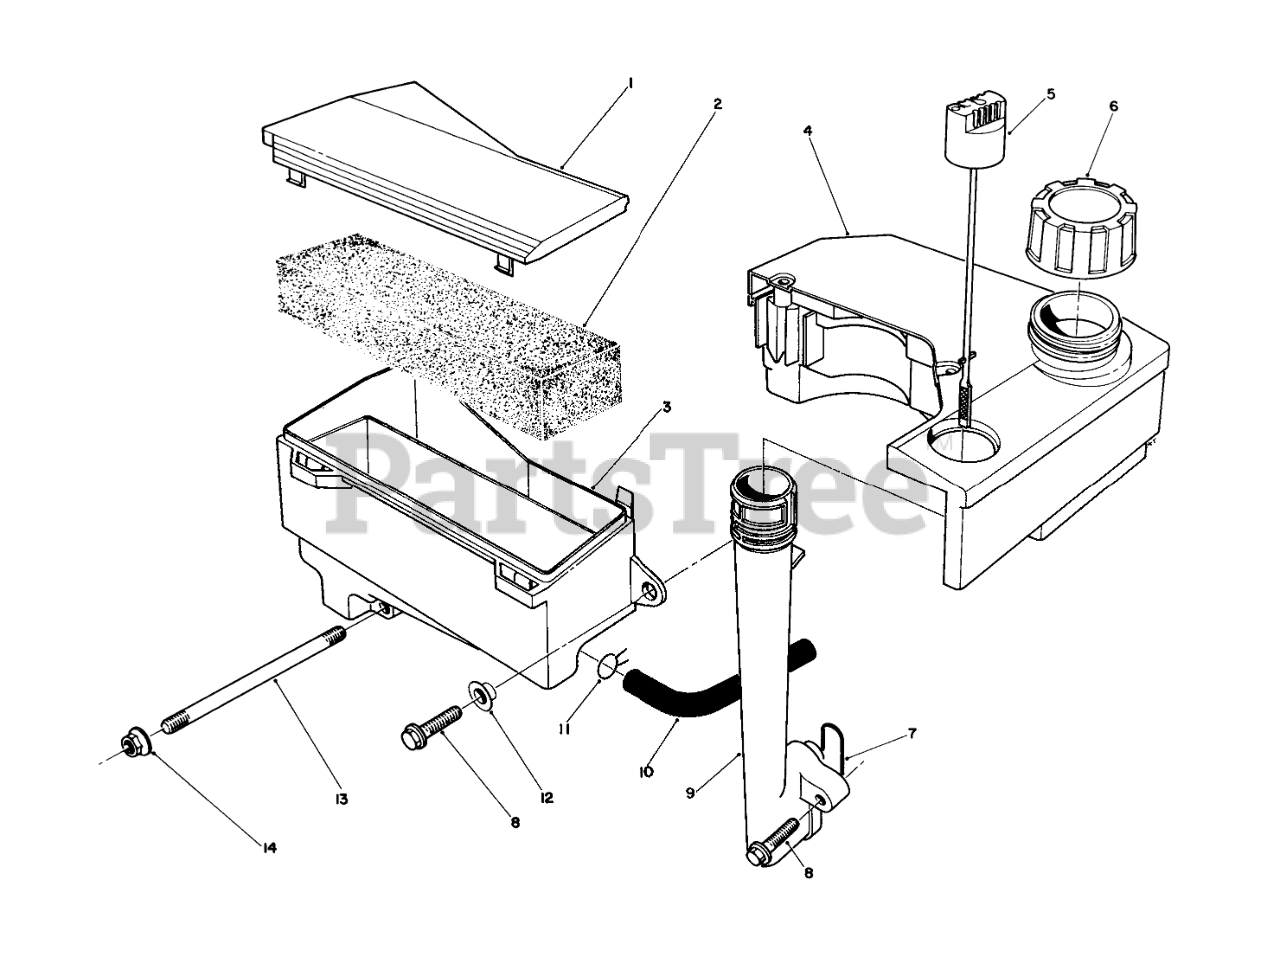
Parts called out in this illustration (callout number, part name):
1	Air Cleaner Assembly (Incl. Ref. #3)
3	Body-Air Cleaner
4	TANK ASM
5	Dipstick
6	GAS CAP ASM
7	O-RING
11	CLAMP F/W ENGINE
12	SPACER
13	Stud-Carburetor
